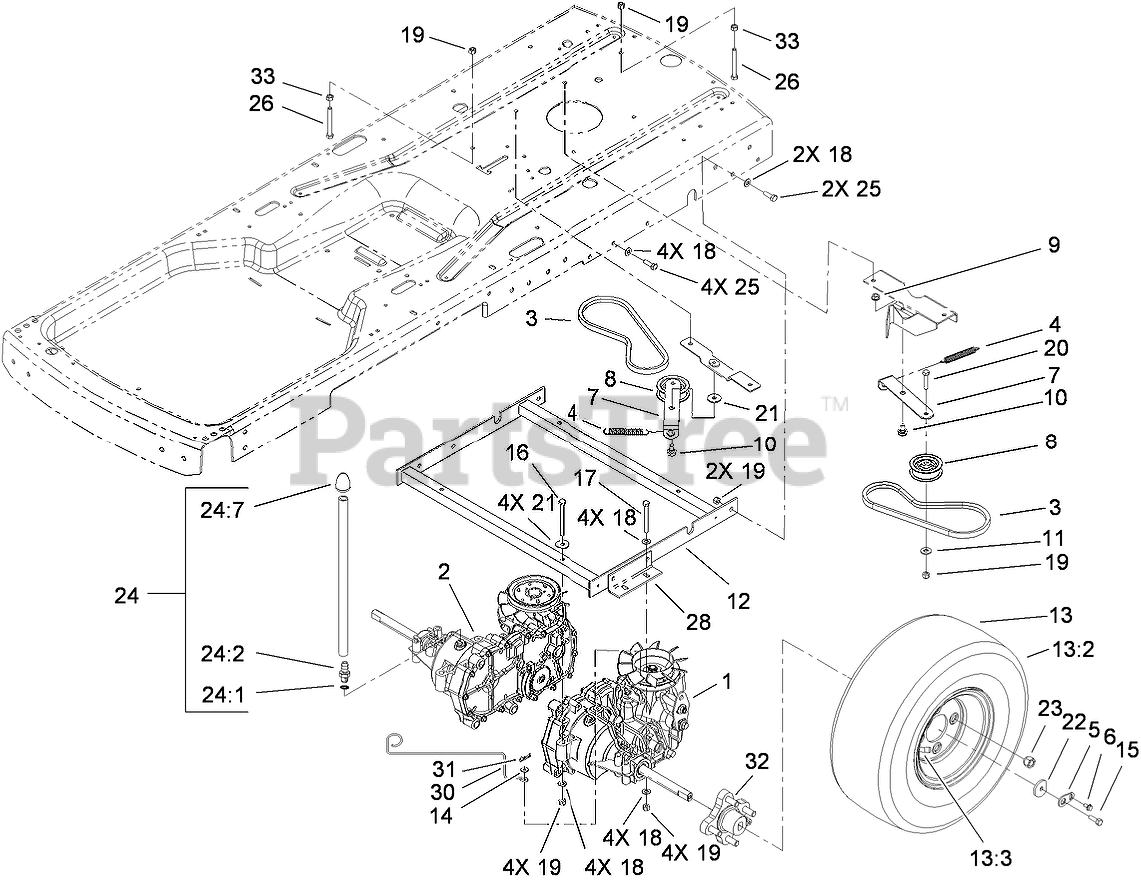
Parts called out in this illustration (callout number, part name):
1	TRANSAXLE-HYDRO, LH
2	TRANSAXLE-HYDRO, RH
3	V-BELT
4	SPRING
5	TAB-LOCKING
6	SCREW-HHF
7	ARM-IDLER
8	PULLEY-IDLER
9	NUT-HF
10	BOLT-SHOULDER
11	WASHER-FLAT
12	HYDRO MOUNT ASM
13	WHEEL AND TIRE ASM
13:3	STEM-VALVE
14	WASHER-FLAT
15	SCREW-HH
16	SCREW-HH
17	SCREW-HH
18	WASHER-PLAIN
19	NUT-LOCK, NI
20	SCREW-HH
21	WASHER-PIVOT
22	WASHER-WHEEL
23	NUT-LUG
24	VENT HOSE ASM
24:1	O-RING
24:2	FITTING ASM
24:7	CAP VENT ASM
25	SCREW-HH
26	SCREW-HH
28	SUPPORT-HYDRO
30	ROD-BYPASS
31	PIN-COTTER
32	HUB ASM
33	NUT-HEX
